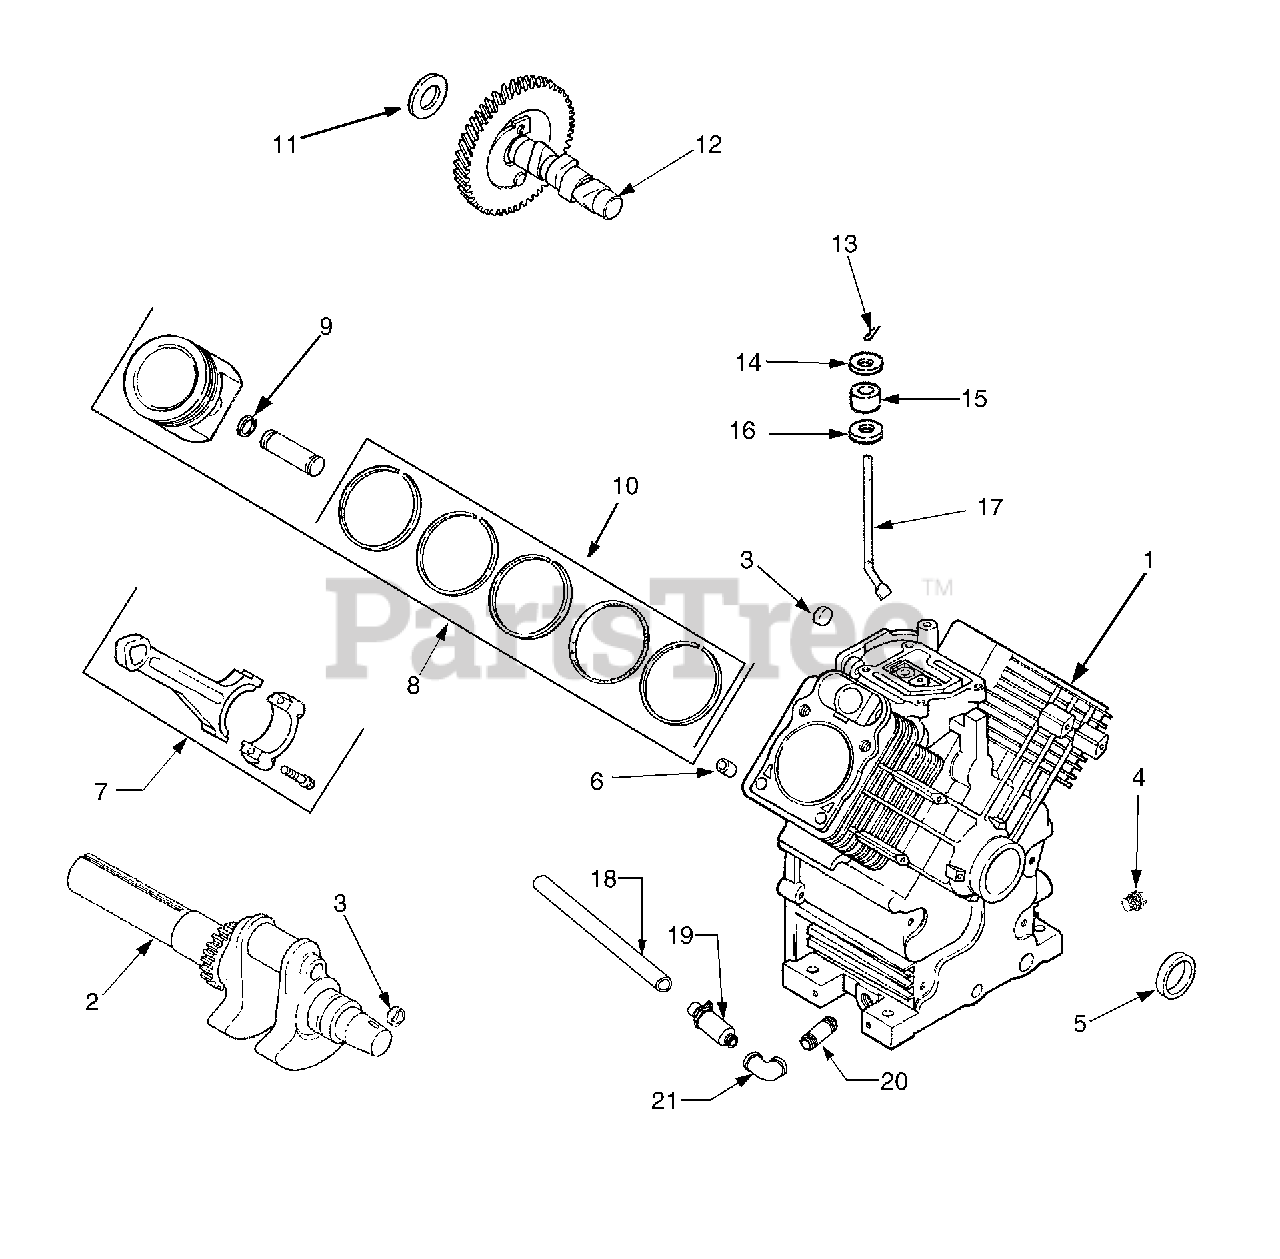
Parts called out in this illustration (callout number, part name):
1	Short Block, 6mm Gov. Shaft
2	Crankshaft
3	Plug, Cup
4	Plug, Hex Head, 3/8 NPTF
5	Seal, Oil
6	Pin, Dowel Locating
7	Rod, Connecting, Std
8	Piston w/Ring Set, Std
9	Retainer, Piston Pin
10	Ring Set, Std
11	Shim, Camshaft, .0320
12	Camshaft
13	Pin, Hitch, 6mm Gov. Shaft
14	Washer, Plain, 6mm Gov. Shaft
15	Seal, Gov. Cross Shaft, (6mm)
16	Washer, Plain, (6mm)
17	Shaft, Governor Cross, (6mm)
18	Hose, Oil Drain, 12 in. Lg.
19	Drain, Oil
20	Pipe, Straight
21	Elbow, 90°.
